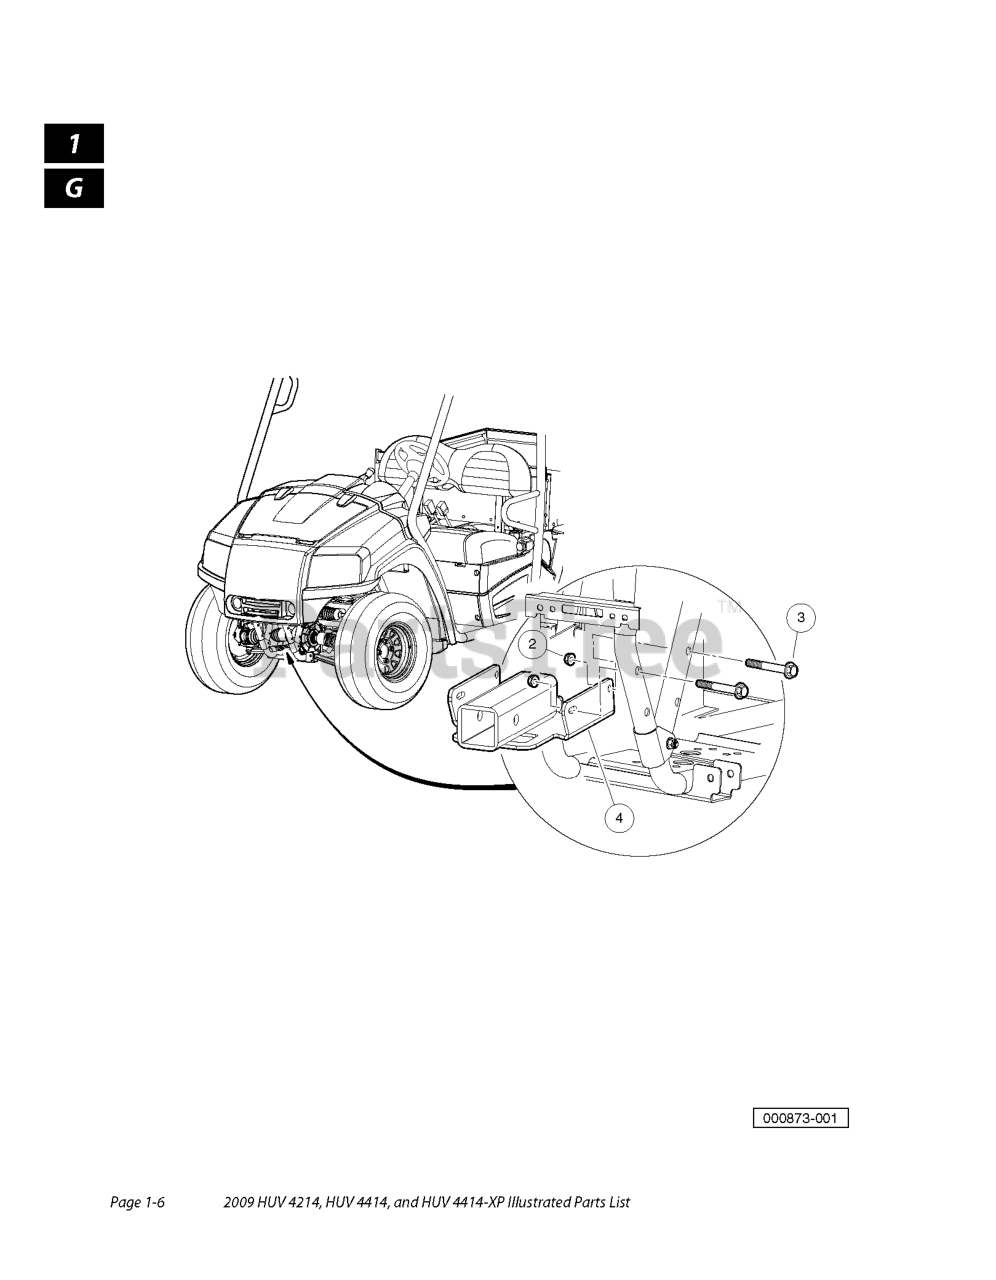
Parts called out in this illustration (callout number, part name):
1	KIT, 2" FRONT RECEIVER
2	NUT FLG M10 X 1.5 NYLON
3	BOLT, FLG, M10X1.5X55, PATCH
